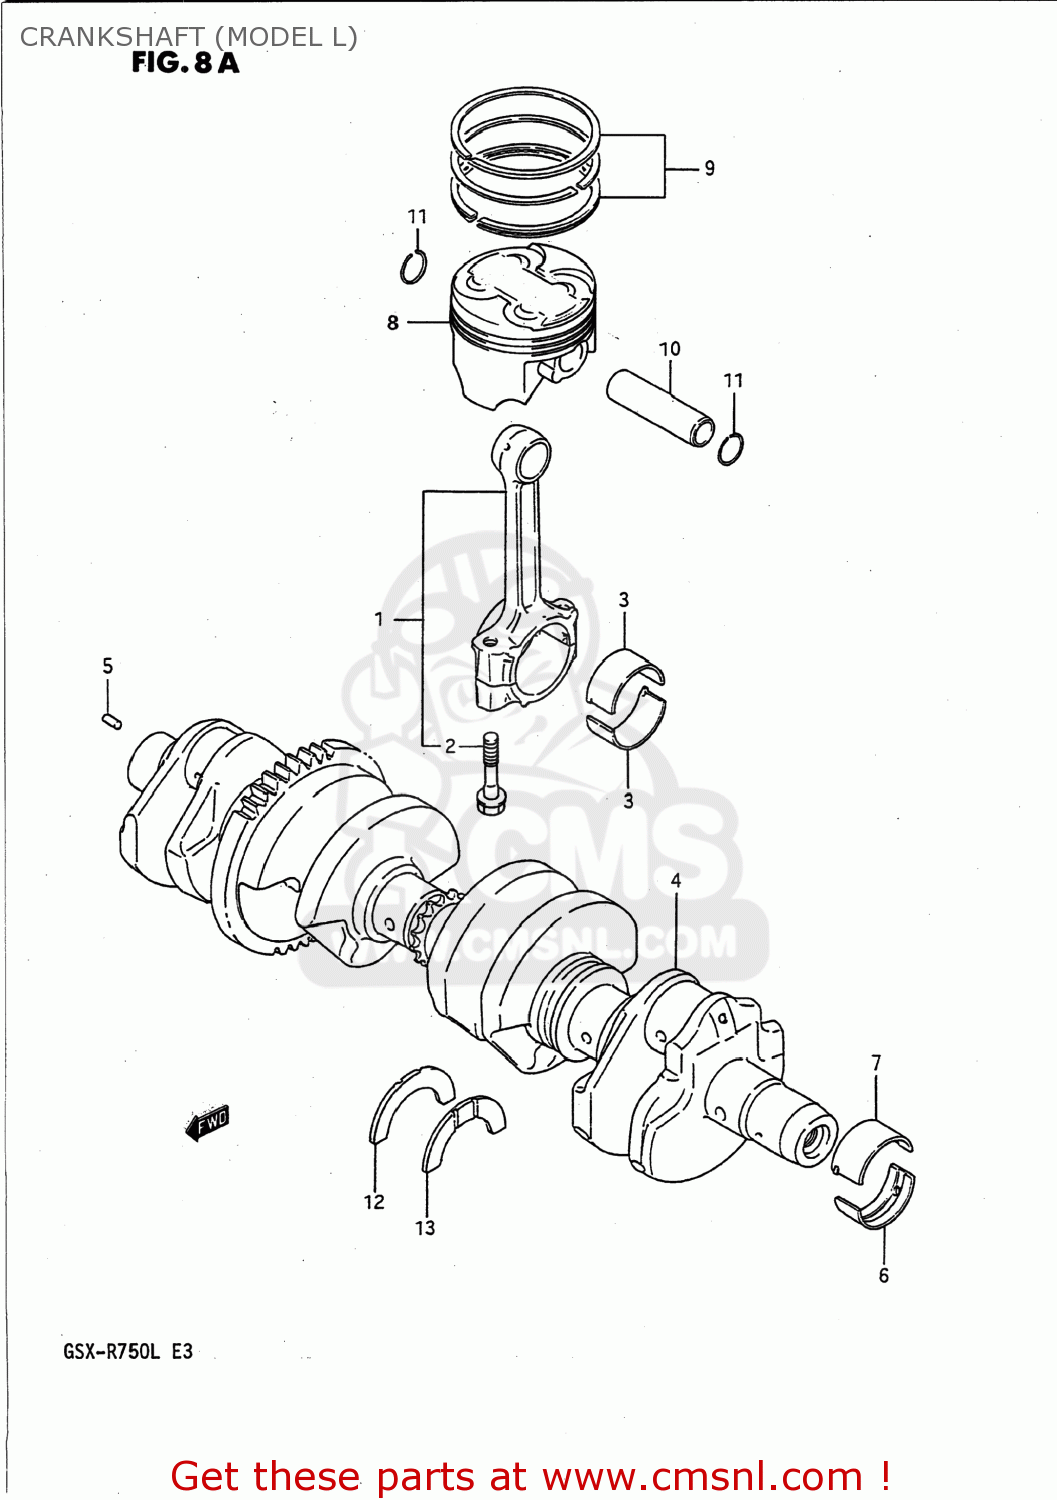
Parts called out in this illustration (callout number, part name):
1	ROD ASSEMBLY,CONNECTING
2	BOLT,CONNECTING ROD
3	BEARING,CRANK PIN
4	CRANKSHAFT
5	PIN
6	BEARING,CRANKSHAFT LWR
7	BEARING,CRANKSHAFT UPR
8	PISTON
9	RING SET,PISTON
10	PIN,PISTON
11	CIRCLIP
12	PLATE,CRANK THRUST
13	PLATE,CRANK THRUST
